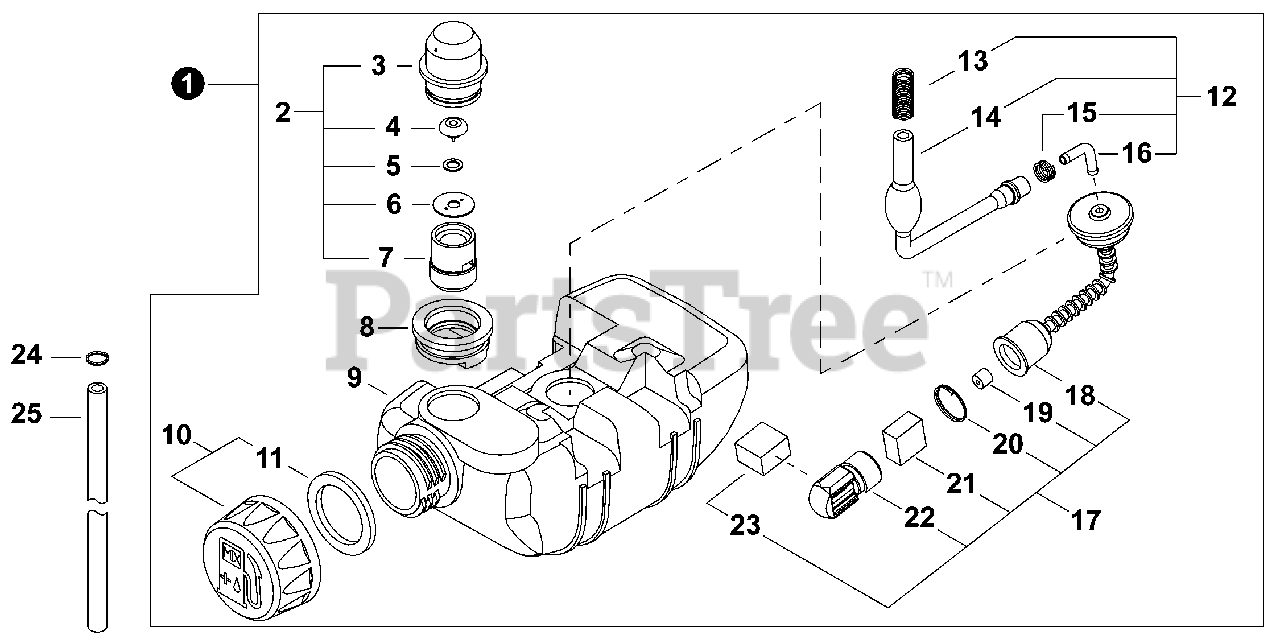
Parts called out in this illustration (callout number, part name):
1	TANK ASSY, FUEL
2	VENT ASSY
3	CAP, VENT
4	VENT ASSY
5	WASHER
6	RETAINER
7	HOLDER, VENT
8	GROMMET, VENT
9	TANK, FUEL
10	CAP ASSY, FUEL
11	GASKET, FUEL CAP
12	LINE ASSY, FUEL
13	CLAMP
14	PIPE, FUEL
15	CLIP
16	CONNECTOR, PIPE
17	FILTER ASSY, FUEL
18	PIPE, FUEL
19	VALVE, CHECK
20	CLIP
21	FILTER, FUEL - B
22	WEIGHT
23	FILTER, FUEL - A
24	CLIP
25	PIPE
